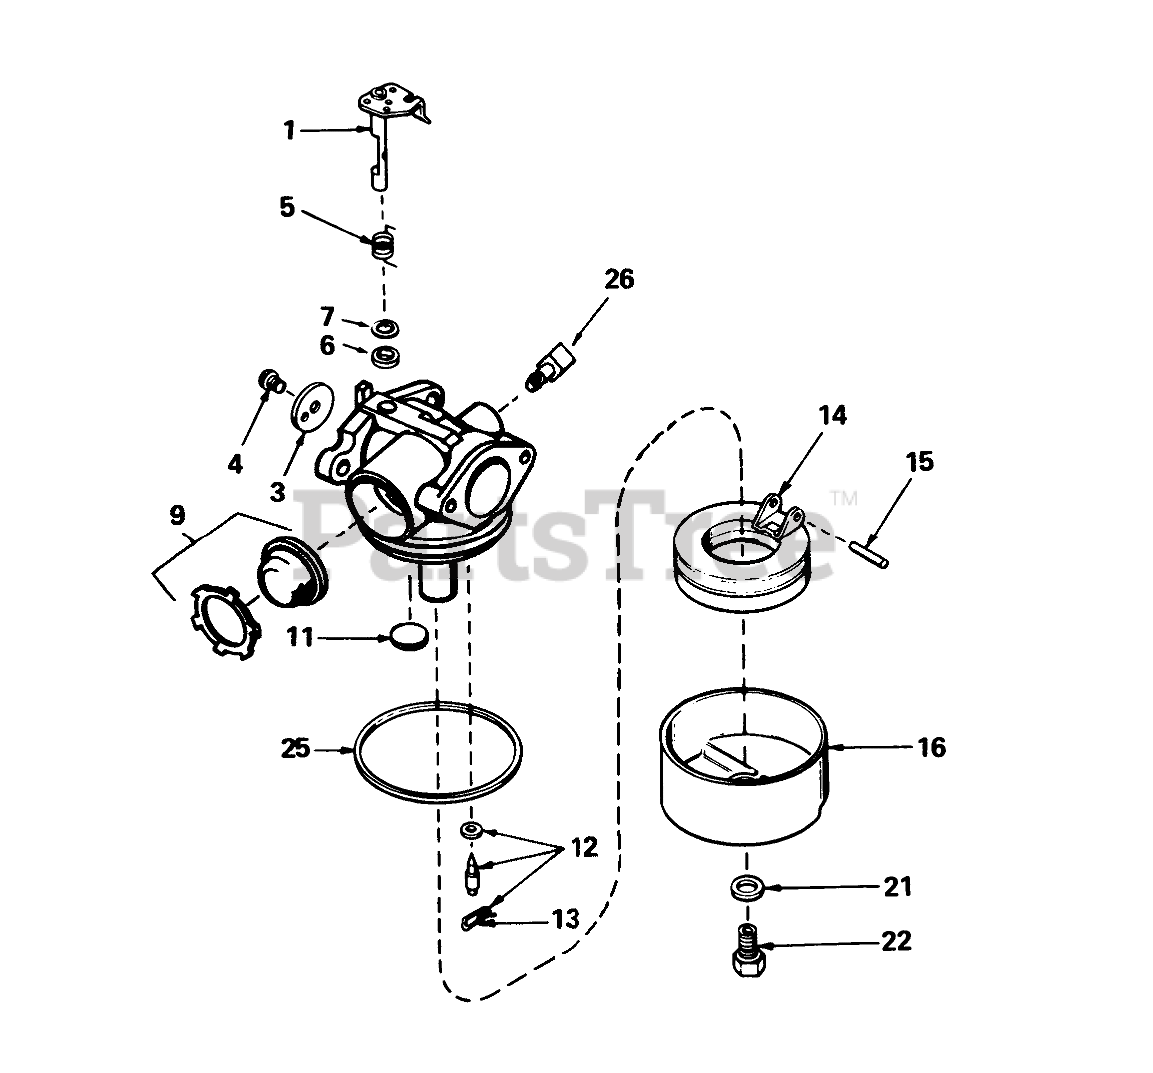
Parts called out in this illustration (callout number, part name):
1	Throttle Shaft and Lever ASM
3	Throttle-Shutter
4	Screw-Shutter
5	Spring-Return, Throttle
6	Seal-Dust
7	Washer-Seal, Dust
9	Primer Assy.
11	Plug-Welch, Atmospheric Vent
12	Inlet Needle-Seat & Clip Assy. (Incl. Ref. #13)
13	Clip-Spring
14	Float
15	Shaft-Float
16	Bowl Float
21	Gasket-Bowl
22	Nut-Float Bowl
25	O Ring-Bowl, Float
26	Fitting-Fuel
